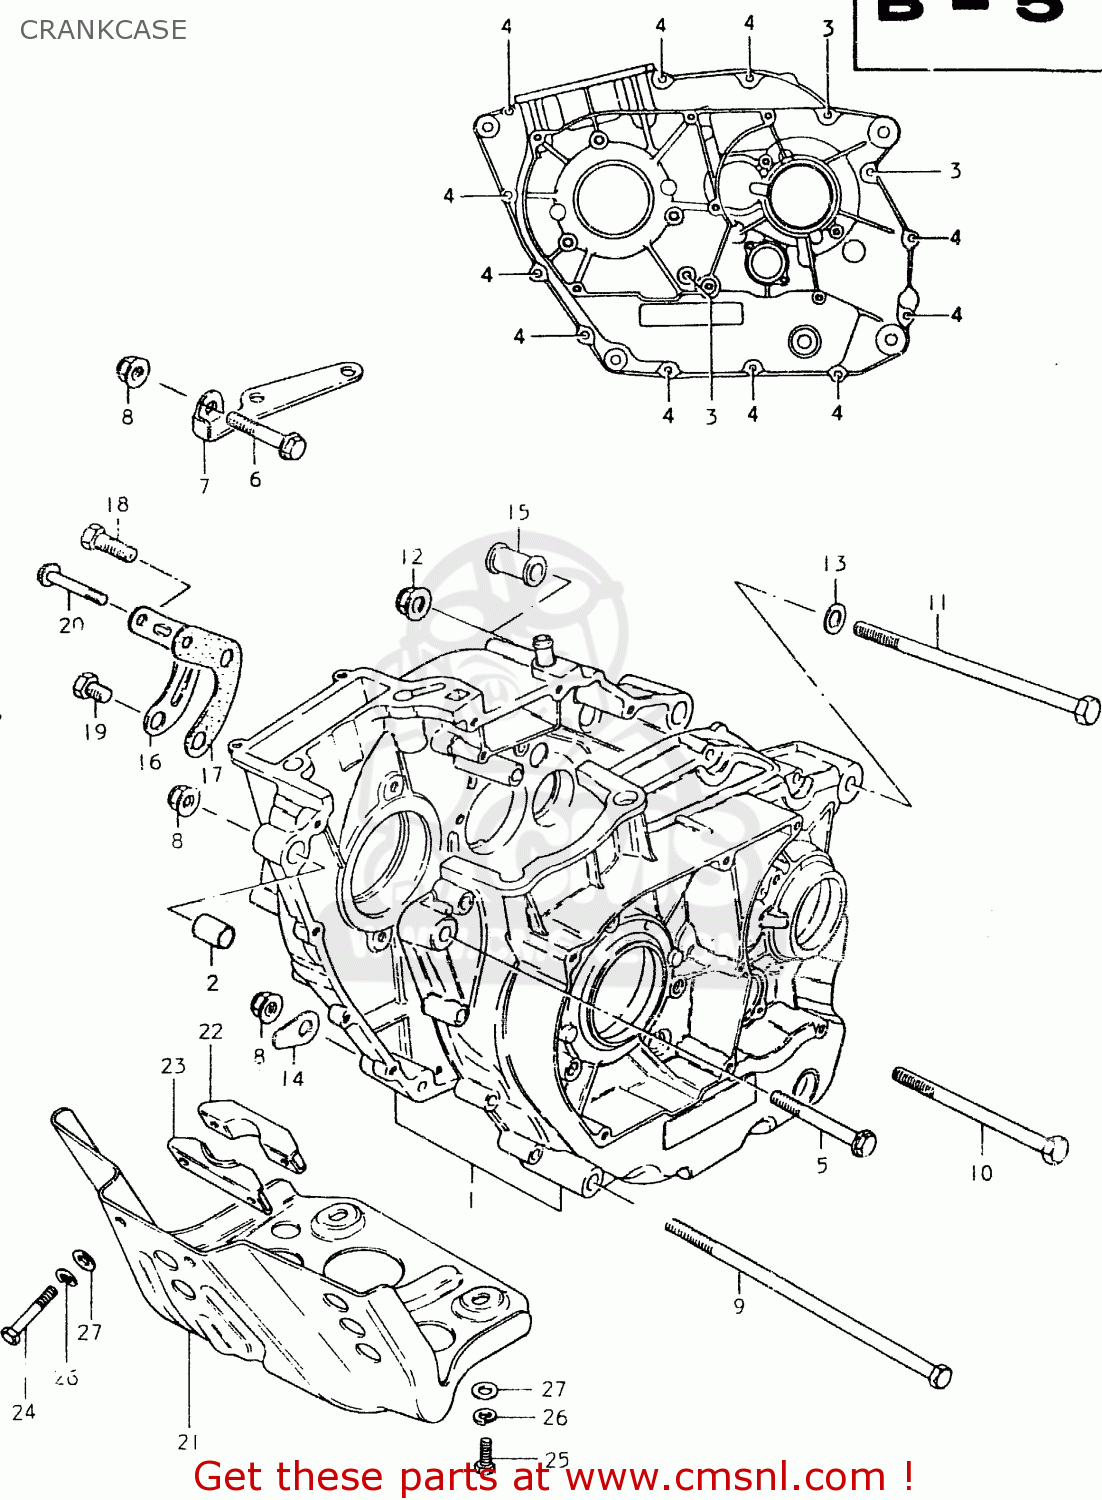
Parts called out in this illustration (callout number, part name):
1	CRANKCASE SET
2	PIN
3	SCREW
4	SCREW (6X35)
5	BOLT (8X70)
6	BOLT
7	PIPE,CYLINDER HEAD OIL
8	NUT
9	BOLT(10X190)
10	BOLT 10X115
11	BOLT 10X155
12	NUT
13	WASHER
14	WASHER
15	SPACER
16	CAP,OIL GALLERY
17	GASKET,OIL GALLERY (MCA)
18	BOLT,UNION
19	PLUG
20	BOLT
21	PROTECTOR,ENGINE
22	BRACKET,ENGINE PROTECT
23	BRACKET,ENGINE PROTECT
24	BOLT
25	BOLT, UPPER
26	LOCK WASHER
27	WASHER
